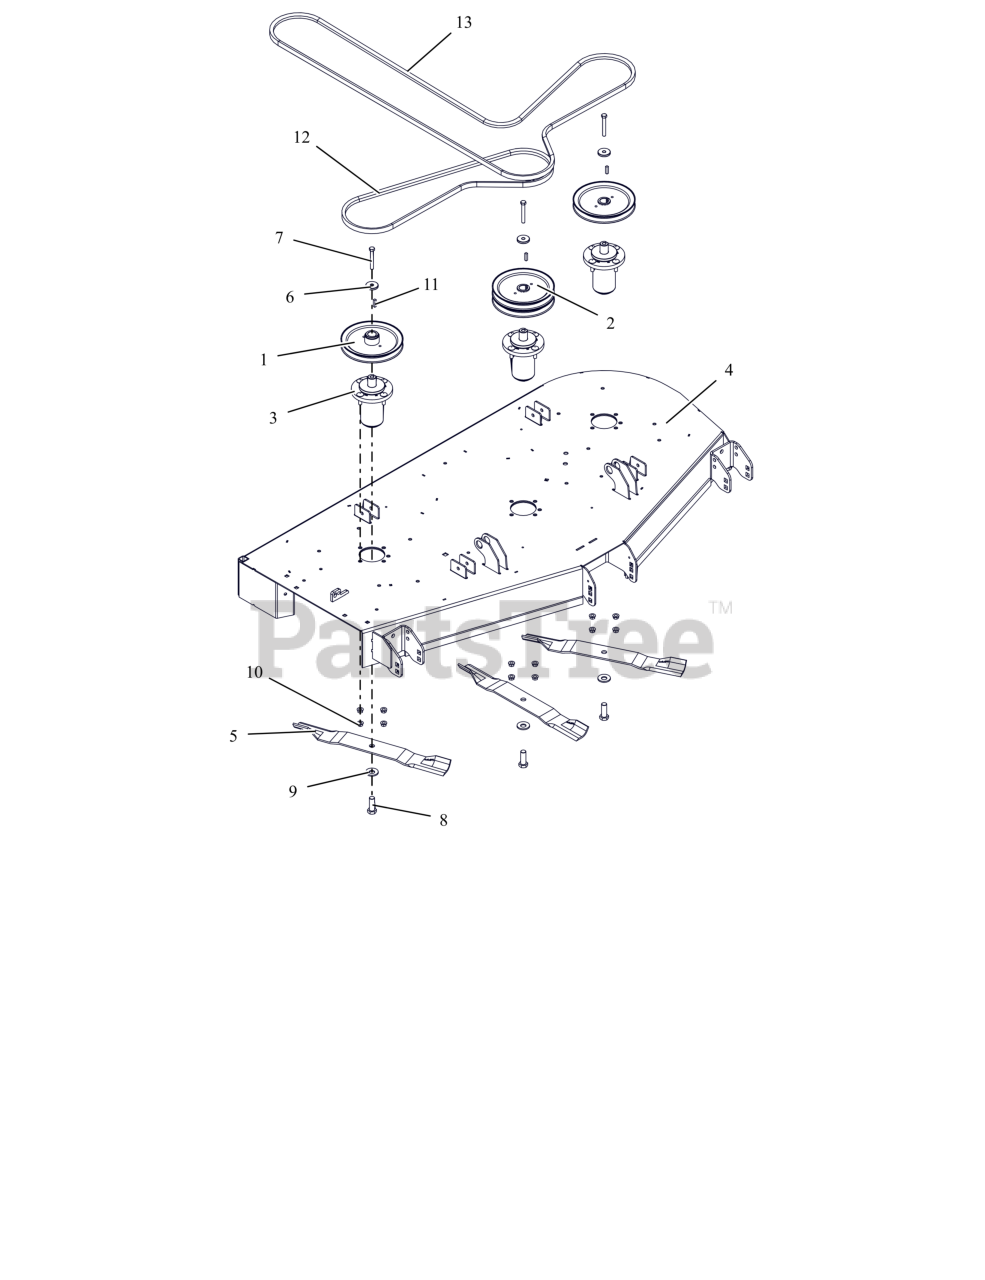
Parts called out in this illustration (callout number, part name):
1	PULLEY- V-7.50 OD X 1" ID
2	PULLEY- DOUBLE-1"X7.50"&7.50"
3	ASM, MAINT FREE ALUM SPINDLE
4	KIT,DECK-60" CE W/DECALS-ARIENS
5	BLADE, 20.5"
6	RETAINER, SHEAVE
7	BLT, HEX .38-16X2.75 G8 ZCC
8	BLT, HEX .62-18X1.75 G8 ZCC
9	WSHR-BLVL .669X1.535X.138
10	NUT-LK-CTR-FLG .375-16 GF ZCC
11	KEY, SQ .25X.25X1.00 RC 40-50
12	V-BELT, B-COGGED
13	V-BELT, HB SECTION
